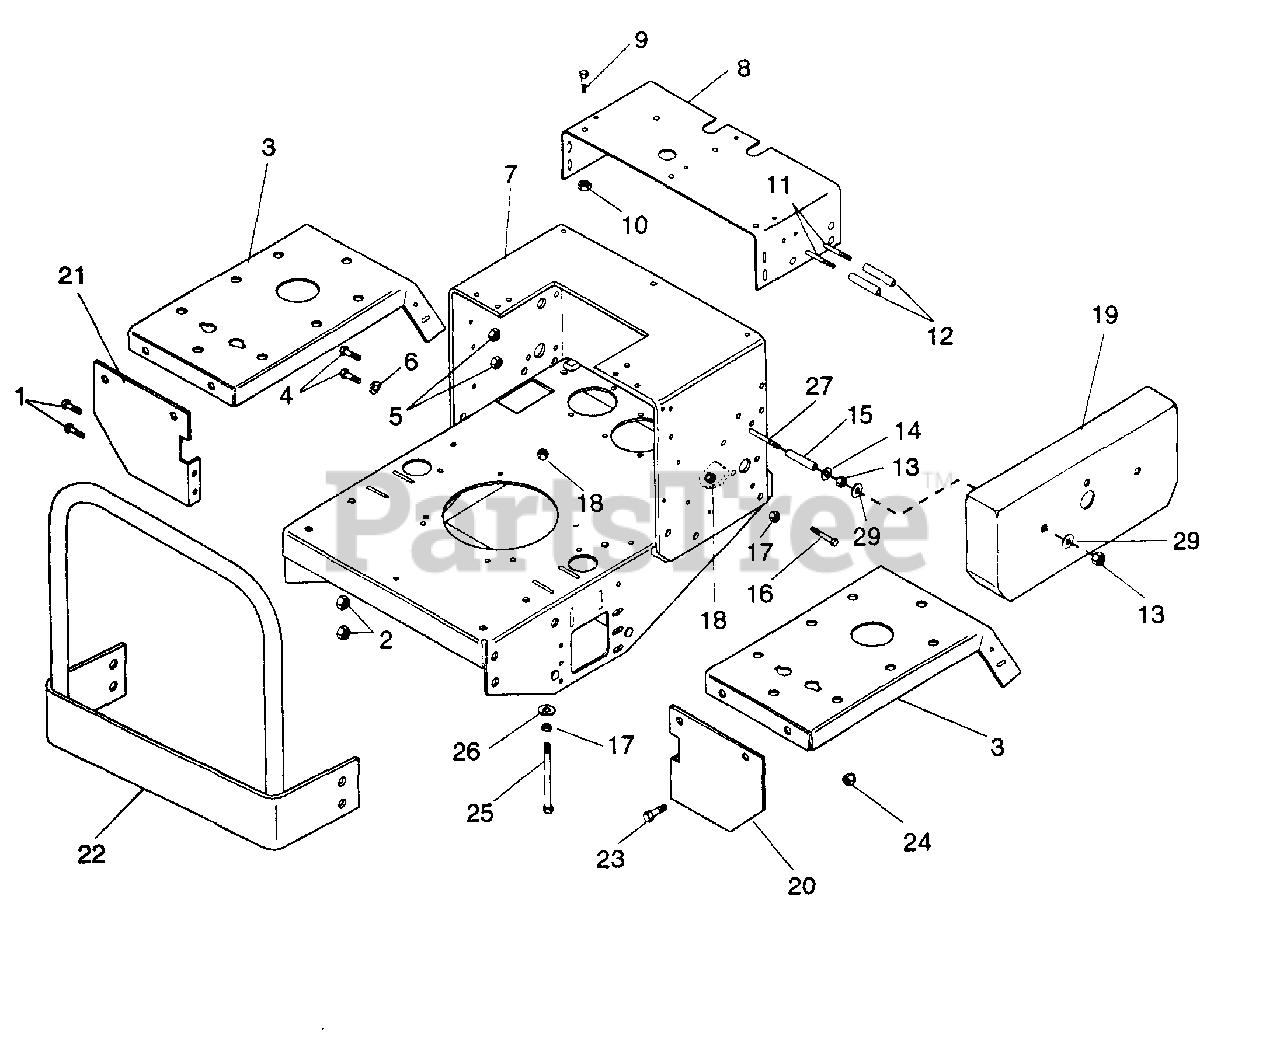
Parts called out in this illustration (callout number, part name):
1	Bolt-Hex .38-16 x 1.25 PL GR. 5
2	Nut-Lock-Nylon .375-16 PL
3	Fender
4	Bolt-Hex .25-20 x .75 PL
5	Nut-Lock-Nylon .250-20 PL
6	Washer-Flat-Steel .281 x .625 x .065
7	Weldment, Frame PM 100
8	Panel, Silkscreen
9	Bolt-Hex .38-16 x 1.00 PL Gr. 5
10	Nut-lock-Nylon .375 - 16 PL
11	Bolt-Hex 5/16 - 18 x 3.75
12	Spacer .328 x .462 x 2.75
13	Nut-Lock-Nylon .312 - 18 PL
14	Washer-Flat Steel .344 x .688 x .065 PL
15	Spacer, .328 x .462 x 2.50 LG
16	Bolt-Hex .38 - 16 x 3.00
17	Nut, Hex .375 - 16
18	Nut-lock-nylon .375 - 16 PL
19	Guard Linkage
20	Support, Fender R. H.
21	Support, Fender L.H.
22	Weldment, Rear Guard
23	Bolt-Hex .31-18 x .75 PL Gr. 5
24	Nut-Lock-Nylon .312-18 PL
25	Bolt-Hex .38-16 x 4.00
26	Washer-Flat-Steel .406x.812x.065
27	Bolt, Hex 5/16-18 x 3.75
28	Decal, Promaster 100
29	Washer-Flat-Steel .313 x .875x.065
